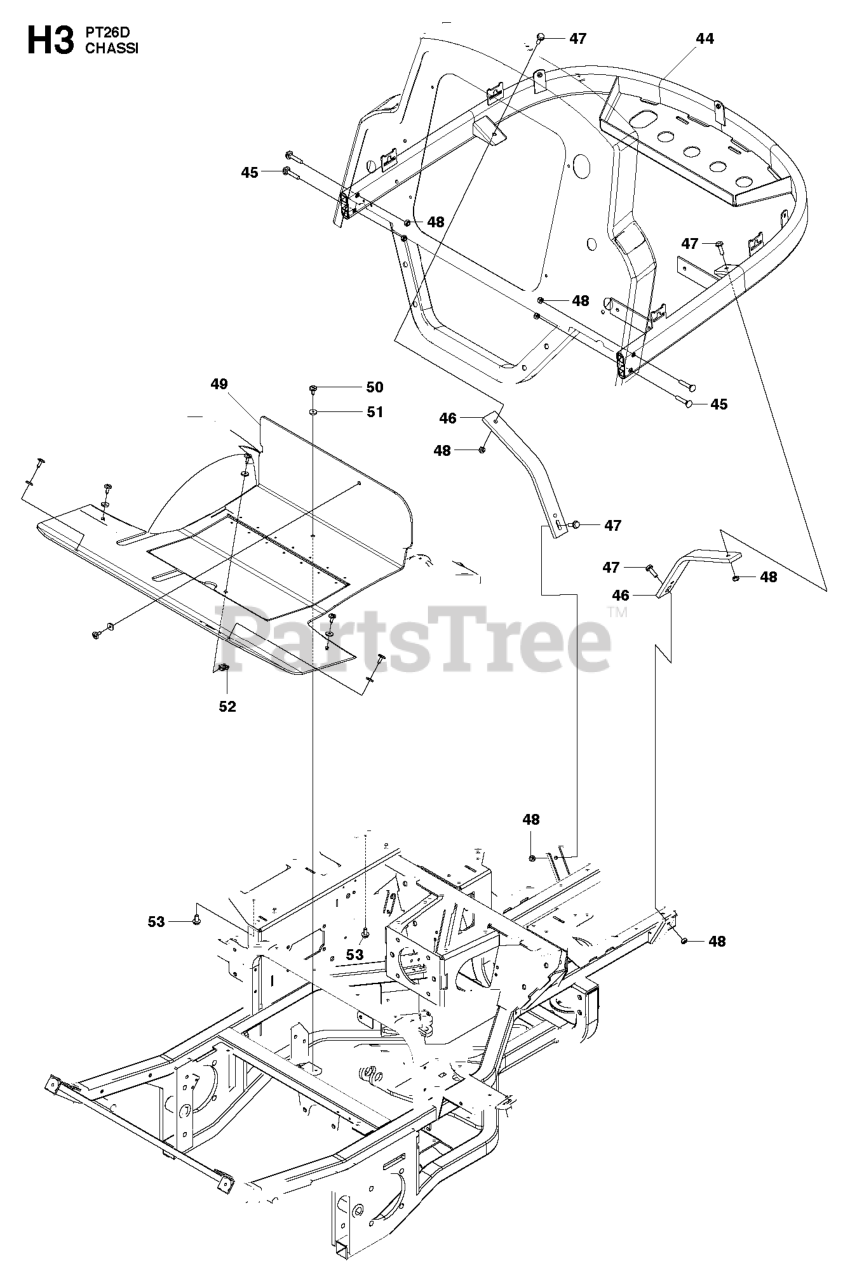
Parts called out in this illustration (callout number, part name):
45	Screw Mvbf 8 X 40
47	BOLT
48	LOCKNUT M8
